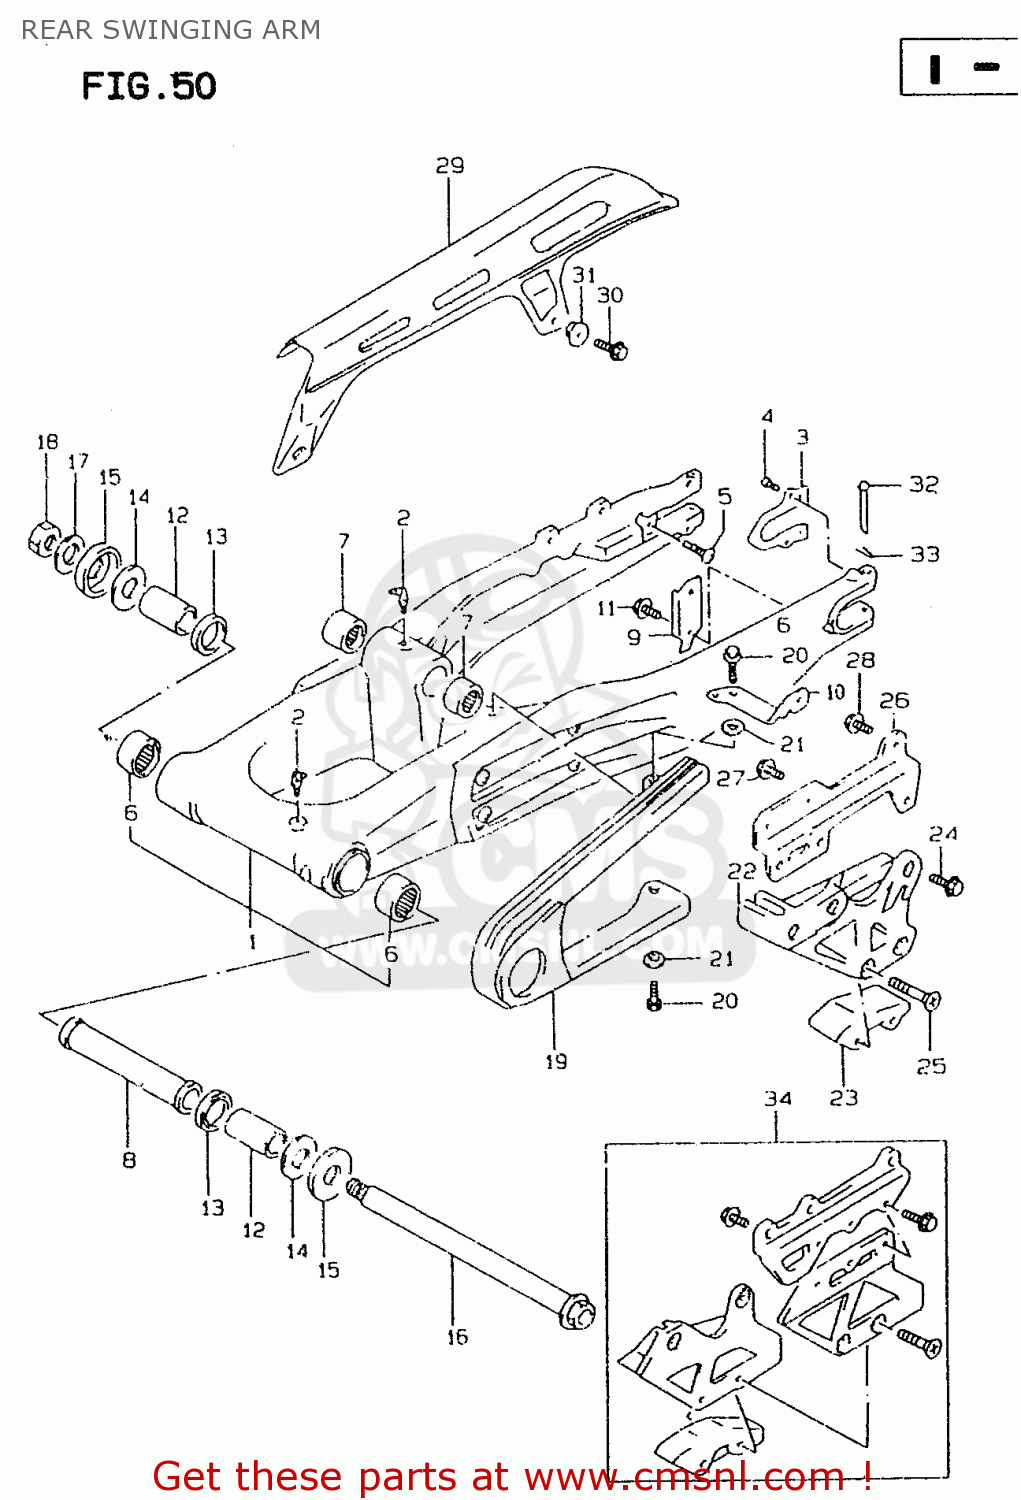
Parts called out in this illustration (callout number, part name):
1	SWINGINGARM ASSY,RR
2	NIPPLE,GREASE
3	PLATE,SWING ARM RR
4	SCREW (5X8)
5	SCREW (M10X21)
6	BEARING(22X29X30)
7	BEARING(20X27X23.5)
8	SPACER,SWING ARM PIVOT,CENTER
9	PLATE,CHAIN CASE FTG RR
10	PLATE,CHAIN CASE FTG FR
11	BOLT
12	SPACER,SWGARM PIVOT BRG
13	SEAL,OIL(22X29X4)
14	WASHER
15	COVER,SWINGINGARM PIVOT
16	SHAFT,SWINGING ARM PIVOT
17	WASHER, FIXED DRIVE FACE
18	NUT
19	BUFFER,CHAIN TOUCH DEFENSE
20	BOLT
21	WASHER
22	GUIDE,CHAIN
23	DEFENSE,CHAIN GUIDE
24	BOLT
25	SCREW
26	BRACKET,CHAIN GUIDE
27	BOLT
28	BOLT
29	CASE,CHAIN
30	BOLT
31	WASHER
32	PIN
33	CLIP
34	GUIDE SET,CHAIN
